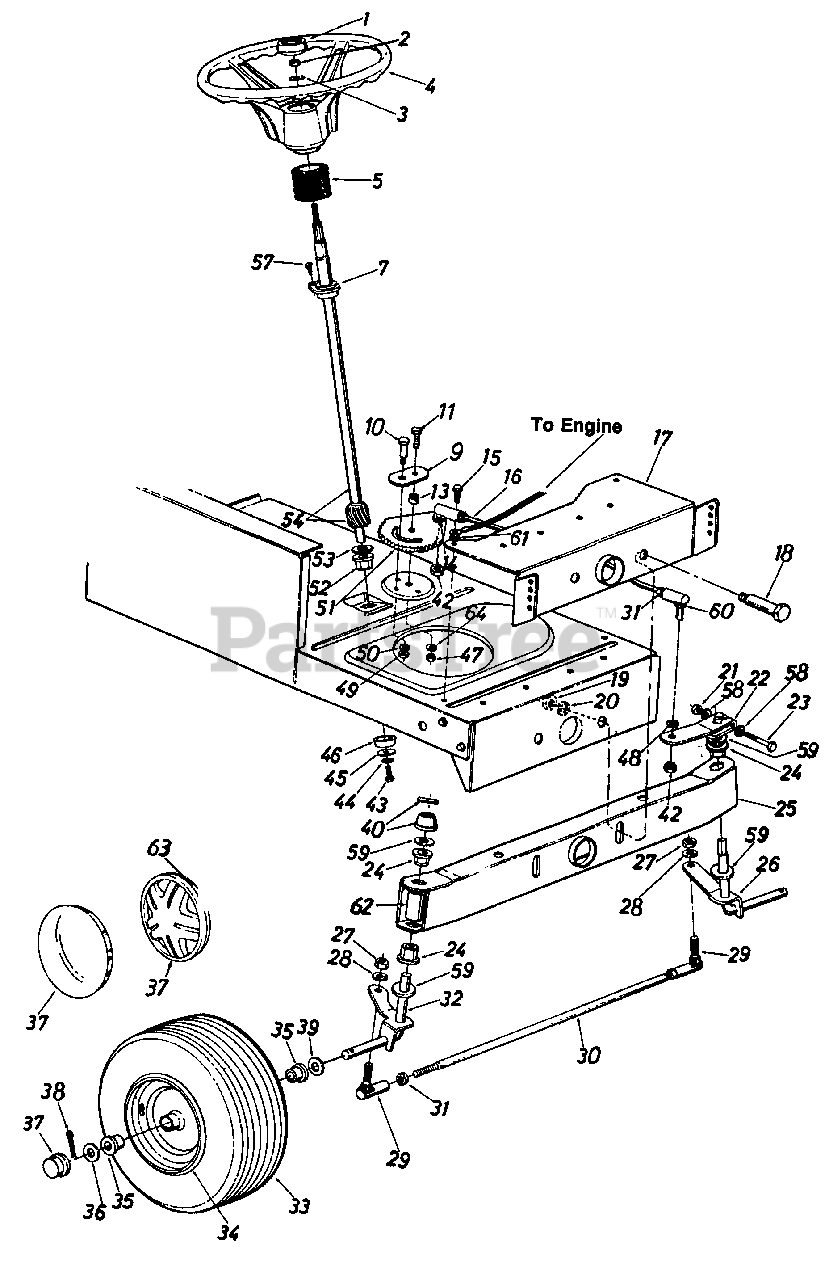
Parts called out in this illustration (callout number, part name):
1	Steering Wheel Cap
2	Hex L-Nut 5/16-24 Thd.
3	Belleville Wash. .345" I.D.
4	Steering Wheel (3 Spoke)
5	Steering Bellow-4.5"
7	Flange Bearing .890 I.D. x 1.36 O.D.
9	Retainer Plate
10	Shoulder Bolt .437" Dia. x .35 Lg. 5/16-18 Thd.
11	Hex Bolt 3/8-24 x 1.0" Lg. (Grade 5)
13	Spacer .380" I.D. x .625" O.D. x .227
14	L-Wash. 3/8" I.D.
15	Hex Wash. Hd. Self-Tap Scr.
16	Steering Drag Link
17	Front Pivot Brkt.
18	Shoulder Bolt .498" Dia. x 2.04 Lg. 3/8-16 Thd.
19	Hex Nut 3/8-16 Thd.
20	L-Wash. 3/8" I.D.*
21	Hex Cent. L-Nut 5/16-24 Thd.
22	Steering Arm Front Axle
23	Hex Bolt 5/16-24 x 2.00" Lg. (Grade 5)
24	Hex Flg. Brg. .634 I.D.
26	Front Axle Ass'y.-L.H.
27	Hex Nut 3/8-24 Thd.
28	L-Wash. 3/8" I.D.
29	Ball Joint 3/8-24 Thd.
30	Tie Rod
31	Hex Jam Nut 3/8-24 Thd.
32	Front Axle Ass'y.-R.H.
33	Wheel Ass'y. Comp.
34	Front Wheel Rim Only
35	Bearing
36	Fl-Wash. .635 I.D. x 1.59" O.D.
37	Front Wheel Hub Cap
38	Cotter Pin 1/8" Dia. x 1.25"
39	Fl-Wash. .640" I.D. x 1.24" O.D.
40	Push Cap 5/8" Dia. Rod
42	Hex Jam Nut 3/8-24 Thd.
43	Hex L-Bolt 5/16-18 x .62"
44	L-Wash. 5/16" I.D.
45	Fl-Wash. .33" I.D. x 1.25" O.D.
46	Spacer (Plastic)
47	Hex Nut 3/8-24 Thd.
48	L-Wash. 3/8" I.D.
49	Hex Nut 5/16-18 Thd.
50	L-Wash. 5/16" I.D.
51	Steering Gear Segment
52	Hex Flg. Brg. .634 I.D.
53	Fl-Wash. (Hardened)
54	Steering Shaft
57	Oval Hd. Cr.-Sunk Scr. #10 x 5/8" Lg.
58	Wave-Wash. .32" I.D. x .62" O.D.
59	Fl-Wash. (Hardened)
60	Drag Link Ball Joint 3/8-24 Thd.
61	Ext. L-Wash. 5/16" I.D.
62	Plastic Tube
63	Spring Clip
64	Bell-Wash. .39" I.D. x 1.38" O.D.
